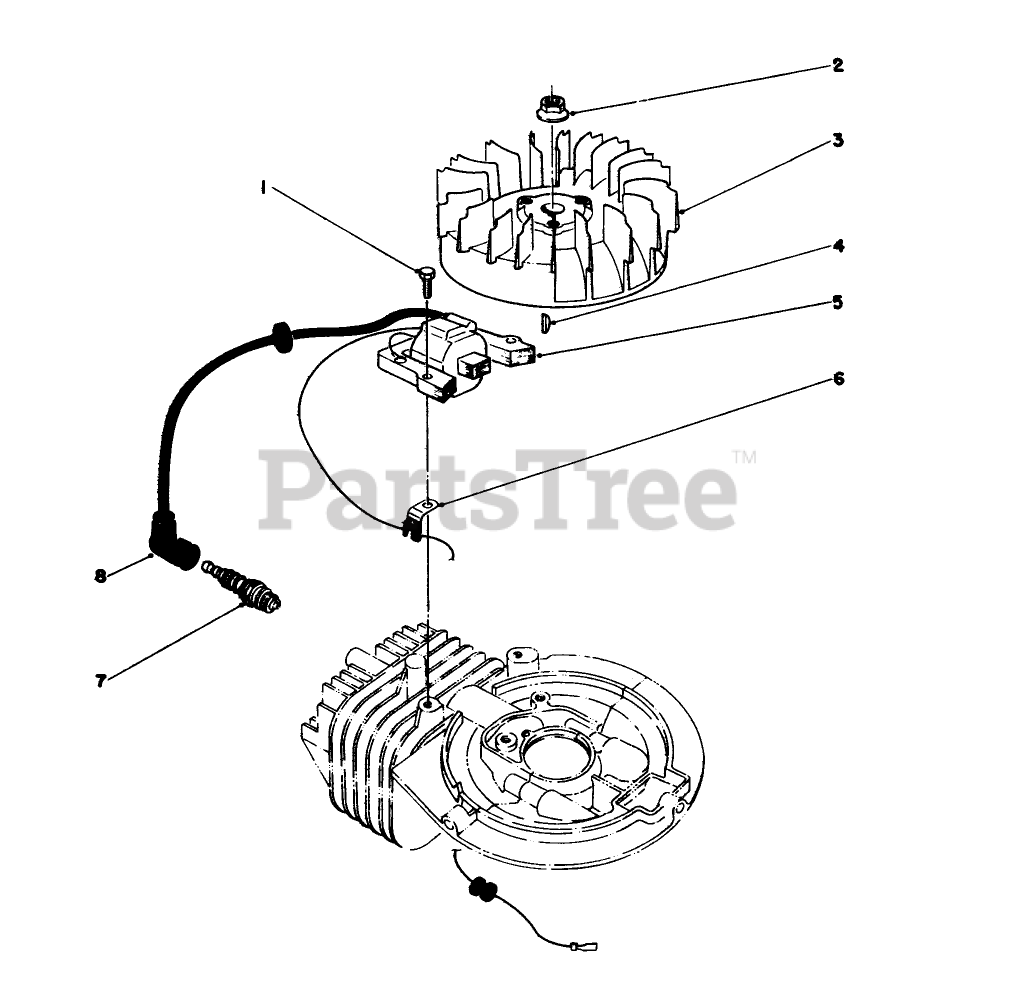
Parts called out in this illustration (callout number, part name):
1	SCREW
3	FLYWHEEL
5	COIL-MAGNETO
6	CLAMP
7	Spark Plug
8	CAP-SPARKPLUG
